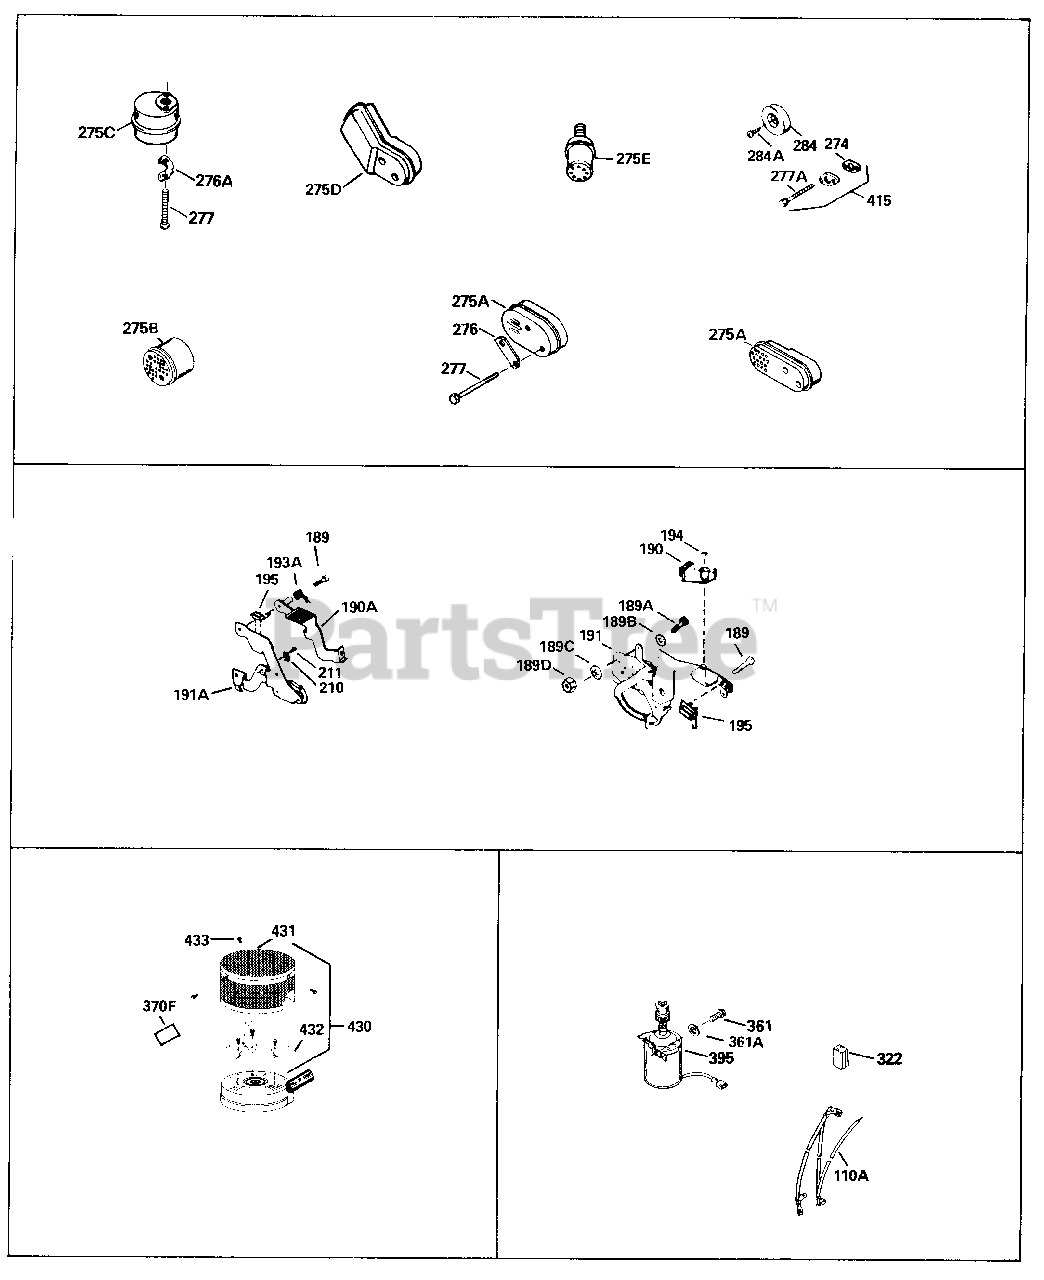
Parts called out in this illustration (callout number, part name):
274	* Gasket, Exhaust (Use as required)
277	Screw, 1/4-20 x 2-1/4"
277A	Screw, T-30, 1/4-20 x 1/2"
370F	Decal, Instruction (Optional)
415	Muffler Adap.Kit (Incl. 274,277A) Use as req.
430	Debris Screen Kit (Incl. 370F,431-433 )(Opt.)
431	Debris Screen (Optional)
432	Debris Screen Bracket (Optional)
433	Screw, 8-32 x 1/4" (Optional)
